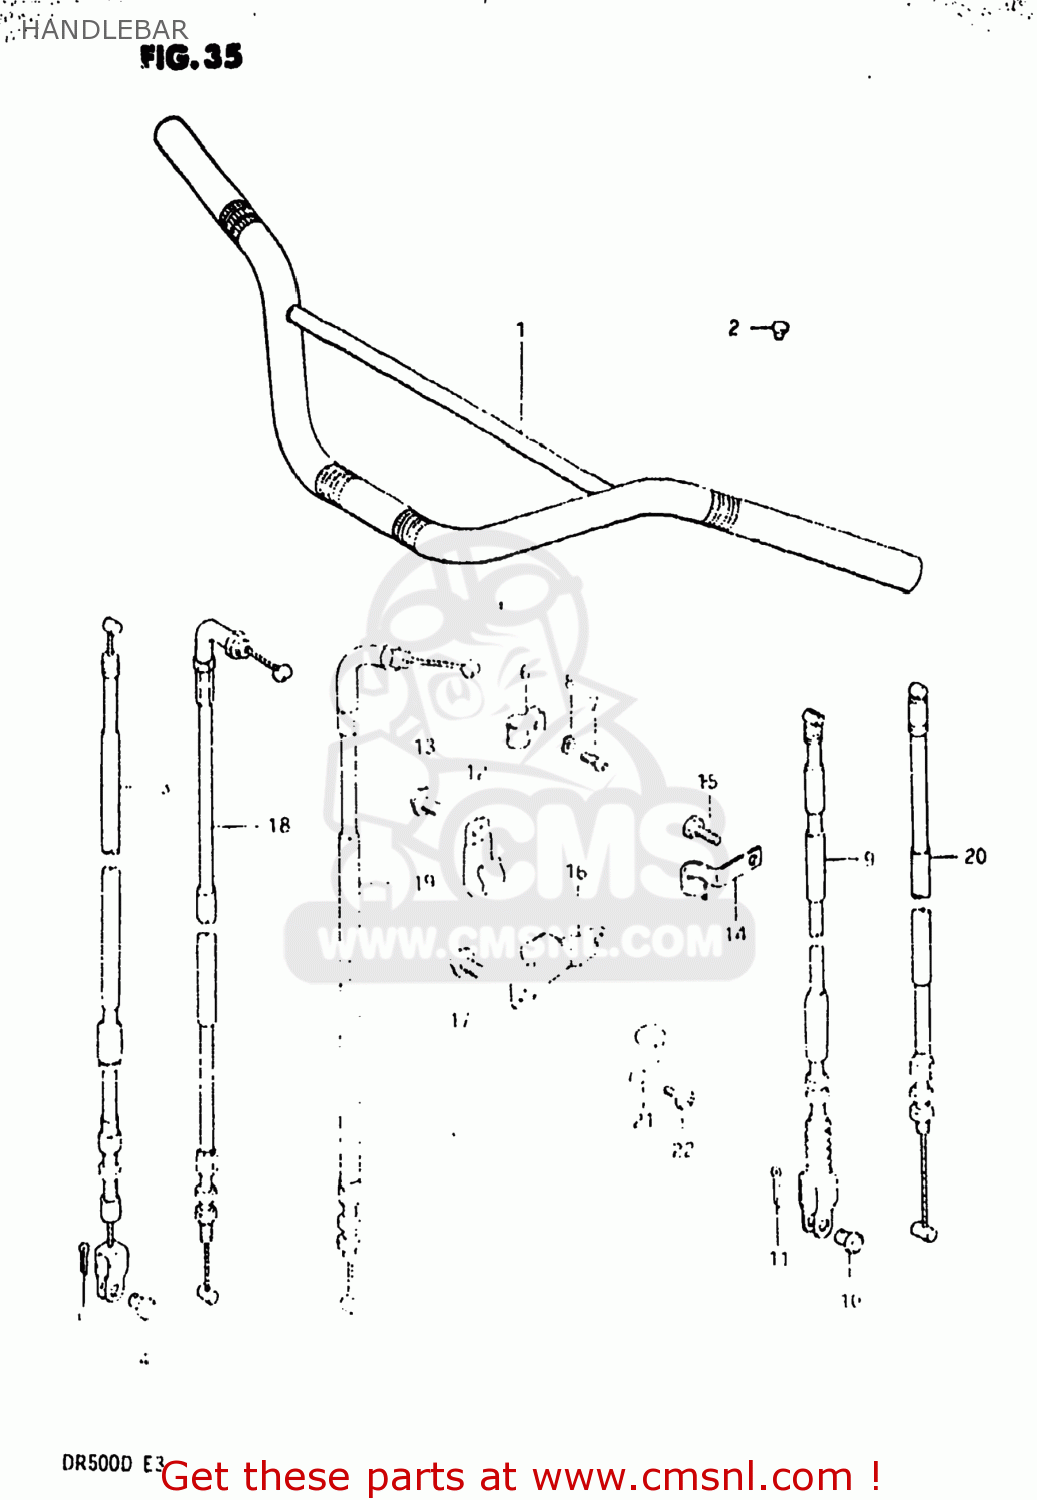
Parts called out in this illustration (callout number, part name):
1	HANDLEBAR
2	CAP(OD:14)
3	CABLE ASSY,FR BRAKE
5	PIN
6	PIN(L:17.5)
7	SCREW
8	LOCK WASHER
9	CABLE ASSEMBLY,CLUTCH
10	PIN(L:15)
11	PIN
12	CLAMP
13	SCREW
14	CLAMP,CLUTCH CABLE NO.1
15	BOLT
16	STOPPER,CLUTCH CABLE
17	SCREW, FRONT
18	CABLE ASSY,THROTTLE NO.1
19	CABLE ASSEMBLY,THROTTLE NO
20	CABLE ASSY,DECOMP
21	GUIDE
22	SCREW
